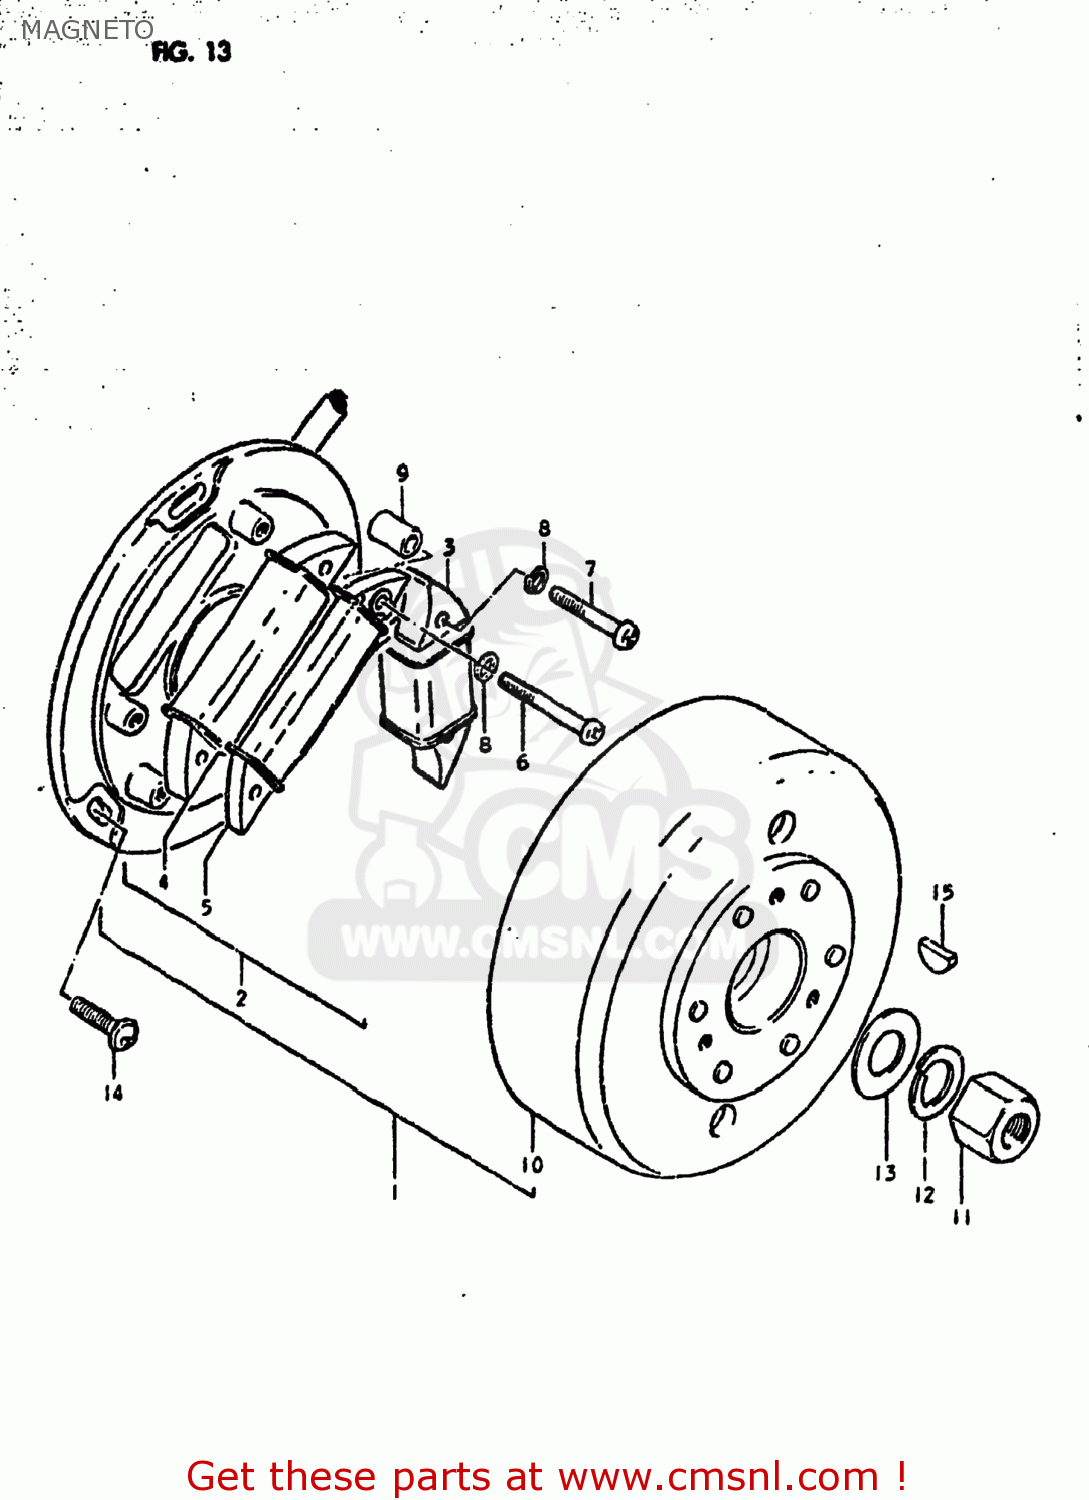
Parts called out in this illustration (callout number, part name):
1	MAGNETO ASSEMBLY
2	STATOR ASSEMBLY
3	COIL,LIGHTING
4	COIL
5	COIL,PULSER
6	SCREW
7	SCREW
8	LOCK WASHER
9	COIL ASSEMBLY,PICK-UP
10	ROTOR ASSEMBLY
11	NUT
12	LOCK WASHER
13	WASHER(14X27X3)
14	SCREW(5X14)
15	KEY 4MM
